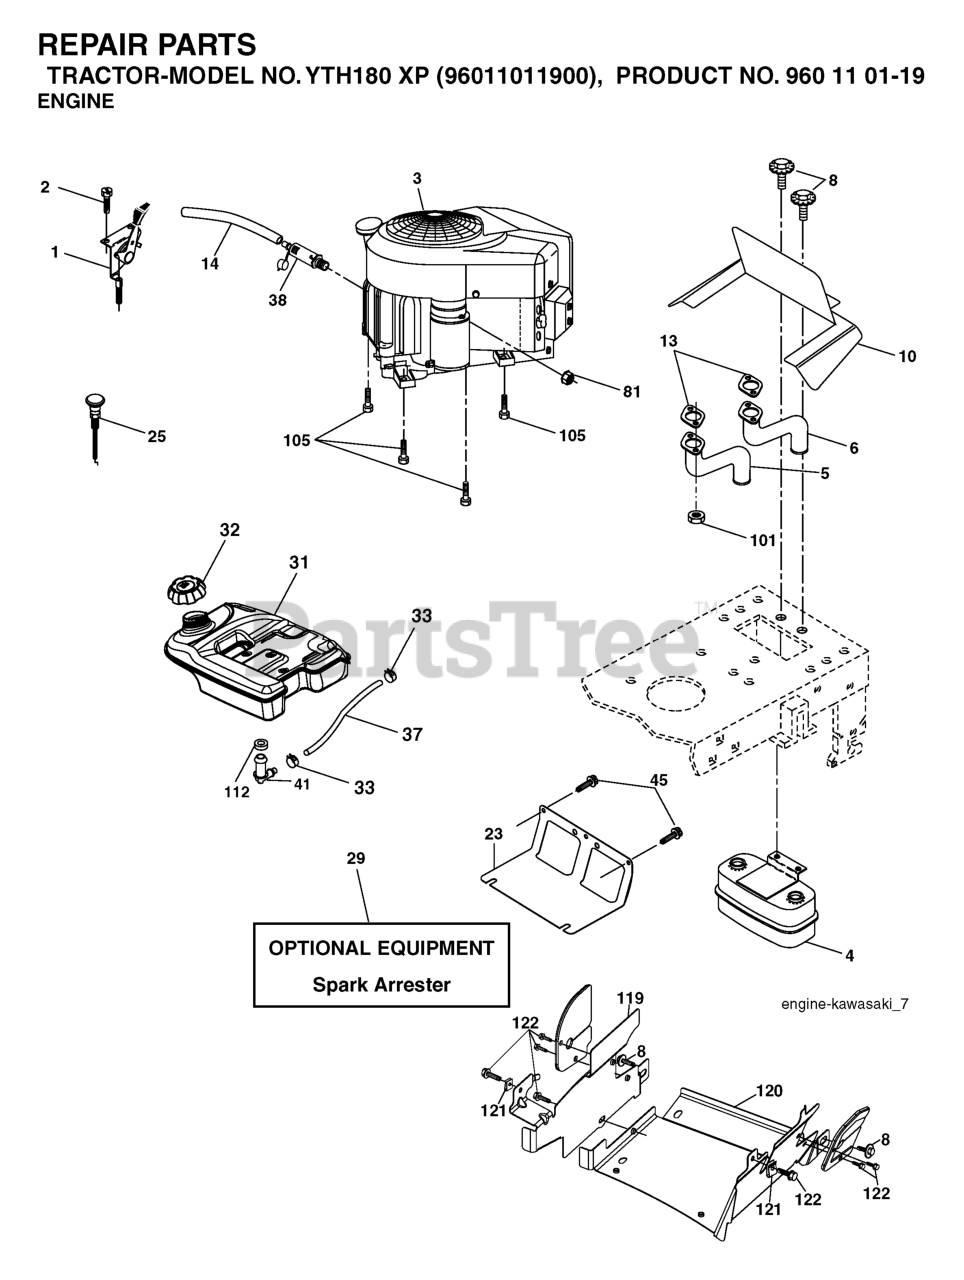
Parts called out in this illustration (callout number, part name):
1	CONTROL, THROTTLE
2	SCREW
4	MUFFLER.TWIN.CYL.LOW.TONE
5	EXHAUST.TUBE.LH.KAWASAKI.
6	EXHAUST.TUBE.RH.KAWASAKI.
8	BOLT.5/16-18UNCX3/4 W/SEMS.BLK
10	RP SHIELD HEAT MUFFLER
14	TUBE, DRAIN OIL ASM.
23	SHIELD.BROWNING.DBR.GUARD
29	KIT.SPARK ARRESTOR 794945 B&S
31	4.0 REAR FUEL TANK
32	TANK CAP
33	HOSE CLAMP
37	REPL BY 532 00 85-43
41	STEM FUEL TANK
45	SCREW, 3/8-16X3/4
81	NUT
101	NUT.HEX.FLANGE.TOPLOCK
105	SCREW 3/8-16X1
112	BUSHING OUTLET T
122	SCREW.1/4-20X5/8
123	SCREW, 5/16-18 X 1/2
